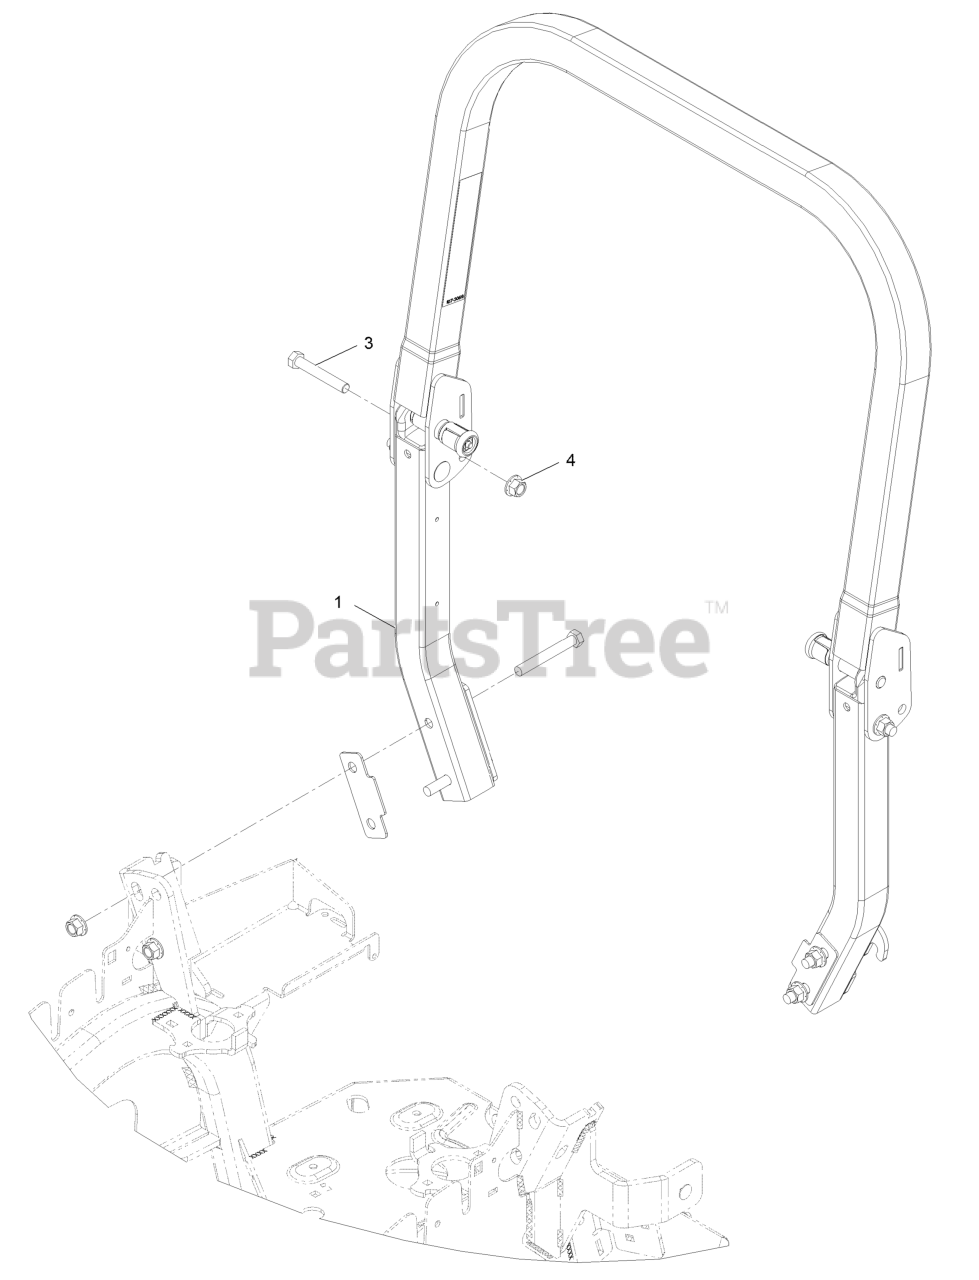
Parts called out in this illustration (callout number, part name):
1	ROPS ASM
3	SCREW-HH
4	Nut-Lock 1/2-13
